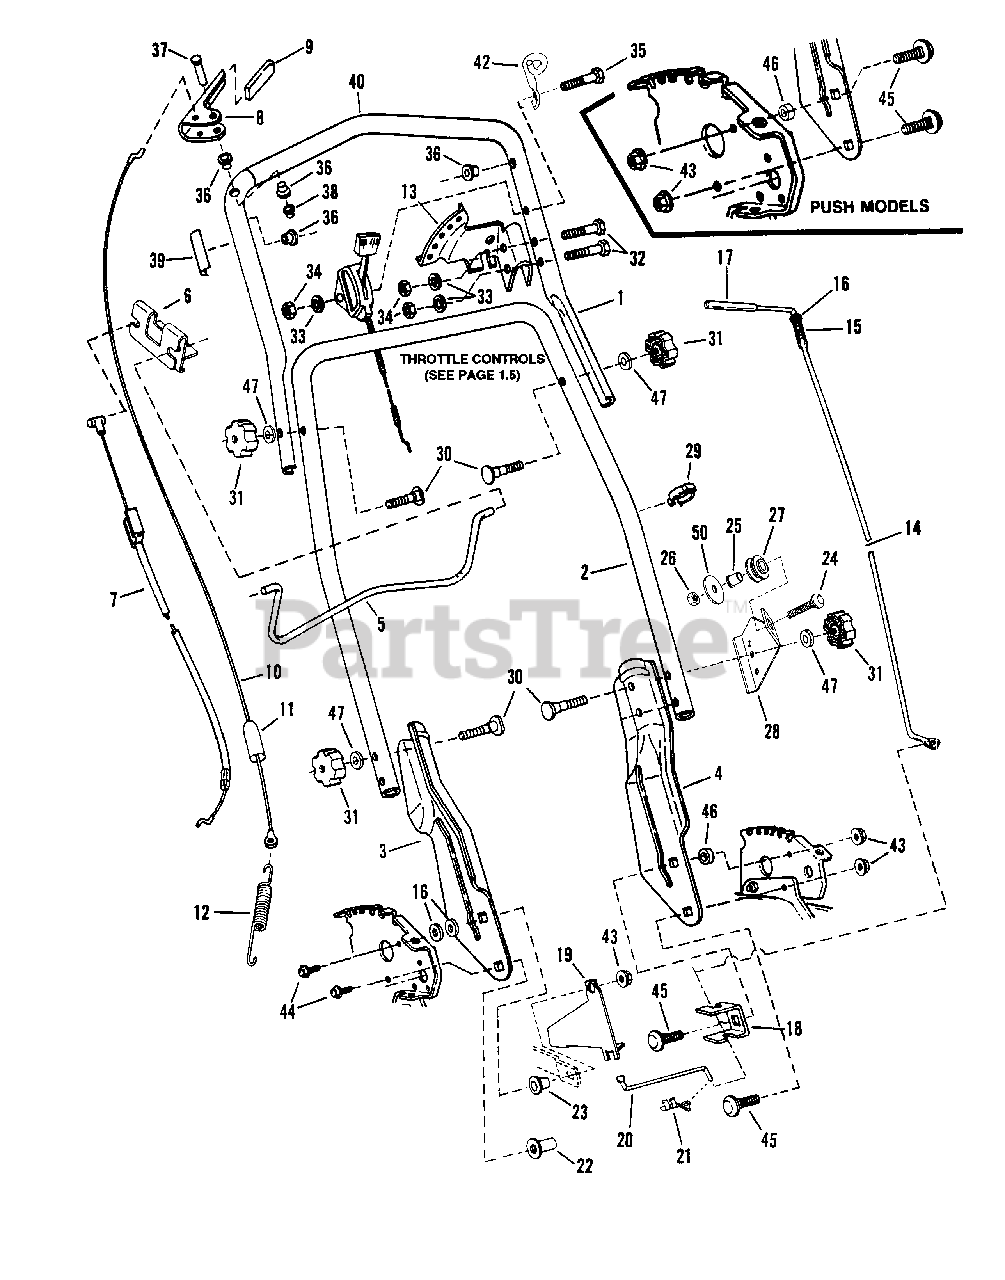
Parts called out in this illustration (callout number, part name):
1	HANDLE, Upper
2	HANDLE, Middle
3	HANDLE, Lower Right Hand
4	HANDLE, Lower Left Hand
5	CONTROL, Blade
6	CLIP, Blade Control
7	CABLE, Blade Control
8	HANDLE, Wheel Drive
9	GRIP, Wheel Drive Handle
10	CABLE, Clutch Pull (Z-Bend)
11	COVER, Vinyl
12	SPRING, Clutch
13	SECTOR, Speed
14	LEVER, Speed Control
15	SPRING, Speed Control
16	WASHER, 3/8" Flat
17	GRIP, Speed Control Handle
18	ANCHOR, Speed Control
19	GUIDE, Lower V-Belt
20	ROD, Transfer
21	CLIP, Transfer Rod
22	TEE-NUT, 5/16-18
23	BUSHING, Differential
24	BOLT, 3/8-16 x 1-1/2" Carriage
25	BUSHING Flange
26	NUT, 3/8-16 Hex Center Lock
27	PULLEY, Nylon
28	BRACKET, Rope Pulley
29	CLIP, Wiring Harness
30	SCREW, 1/4-20 x 1-7/8" Curved Head
31	KNOB, 5/16-18
32	SCREW, 1/4-28 x 1-3/8" Hex Cap
33	WASHER, 1/4 Internal Tooth Lock
34	NUT, 1/4-20 Hex
35	SCREW, 1/4-28 x 2" Hex Cap
36	BUSHING
37	PIN, Clutch Handle
38	NUT, Push (for handle pin)
39	DECAL, Blade Control
40	GRIP, Foam
42	BRACKET, Pull Rope
43	NUT, 5/16-18 Hex Flange Lock
44	BOLT, 5/16-18 x 1" Hex Flange Lock
45	BOLT, 5/16-18 x 1" Carriage
46	SPACER
47	WASHER, 5/16 Internal Tooth Lock
50	WASHER, 3/8 x 2" Flat
